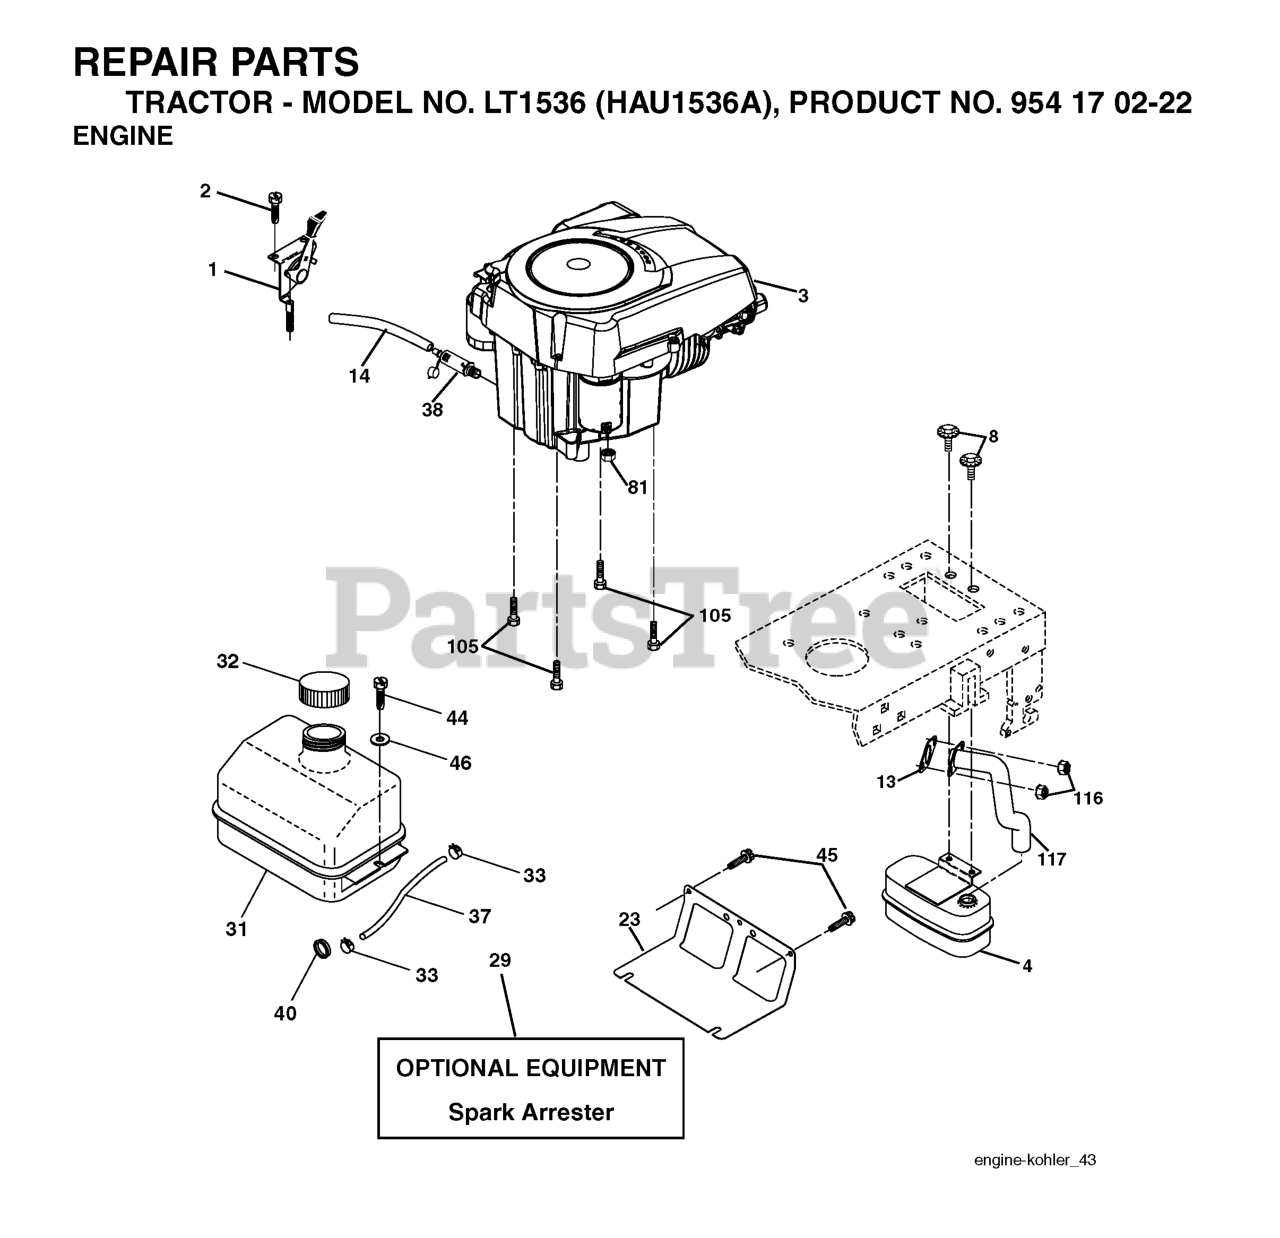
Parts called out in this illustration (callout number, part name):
1	CONTROL.THROTTLE.LT/YT
2	SCREW
4	MUFFLER.SINGLE.CYL.KOHL/B&S
8	BOLT.5/16-18UNCX3/4 W/SEMS.BLK
13	GASKET.EXHAUST.KOHLER
14	TUBE, DRAIN OIL ASM.
23	SHIELD.BROWNING.DBR.GUARD
29	KIT.SPARK ARRESTOR 794945 B&S
31	TANK.ASM.FUEL.FRONT.W/CAP
32	FUEL CAP
33	HOSE CLAMP
37	LINE.FUEL.20
38	PLUG DRAIN OIL EASY
40	BUSHING.SNAP.NYL.BLK.
44	SCREW HEXWSHR 1/4-20X3/4
45	SCREW, 3/8-16X3/4
81	NUT
105	SCREW 3/8-16X1
116	NUT.HEX.FLANGE.TOPLOCK
117	RP.TUBE.EXHAUST.KOHL.COURAGE
